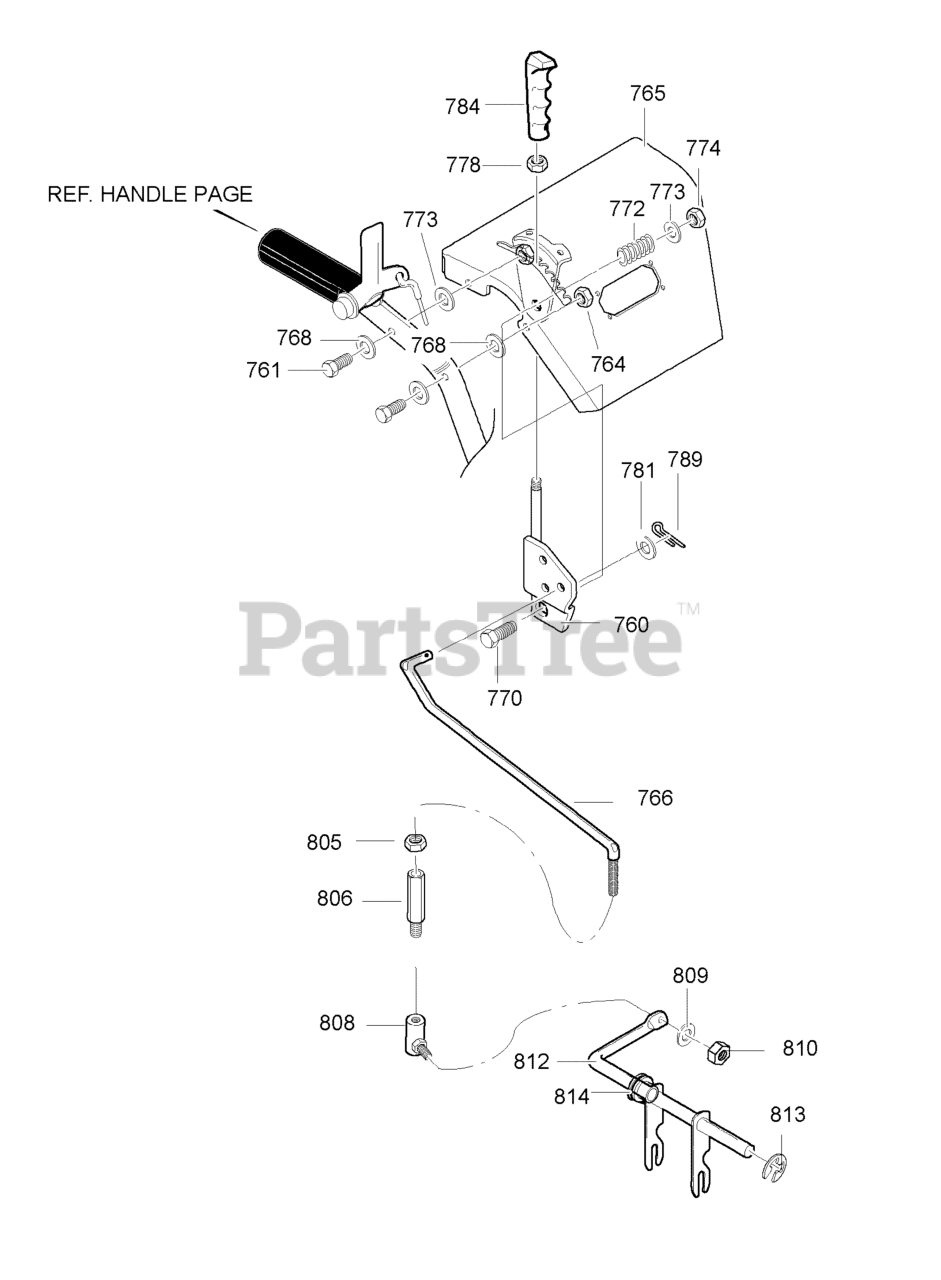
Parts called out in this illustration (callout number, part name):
760	HANDLE ASSEMBLY SPEED CONTROL
761	SCREW, 5/16-18 x 1.75
764	NUT, 5/16-18
765	ASSEMBLY BAY PANEL - LT
766	ROD, SPEED CONTROL
768	WASHER
770	SCREW 3/8-16 X 2.00
773	WASHER, Flat, 13/32
774	NUT, 3/8-16
778	NUT, 3/8-16
781	FLATWASHER
784	HANDLE, GRIP
789	PIN, COTTER
805	NUT, 5/16-18
806	ADAPTER, SPEED ROD -YZ
808	BALLJOINT, STEEL -YZ
809	WASHER
810	NUT, 5/16-18
812	ROD, ASSEMBLY YOKE
813	RING, RETAINER
814	BEARING, FLANGE
